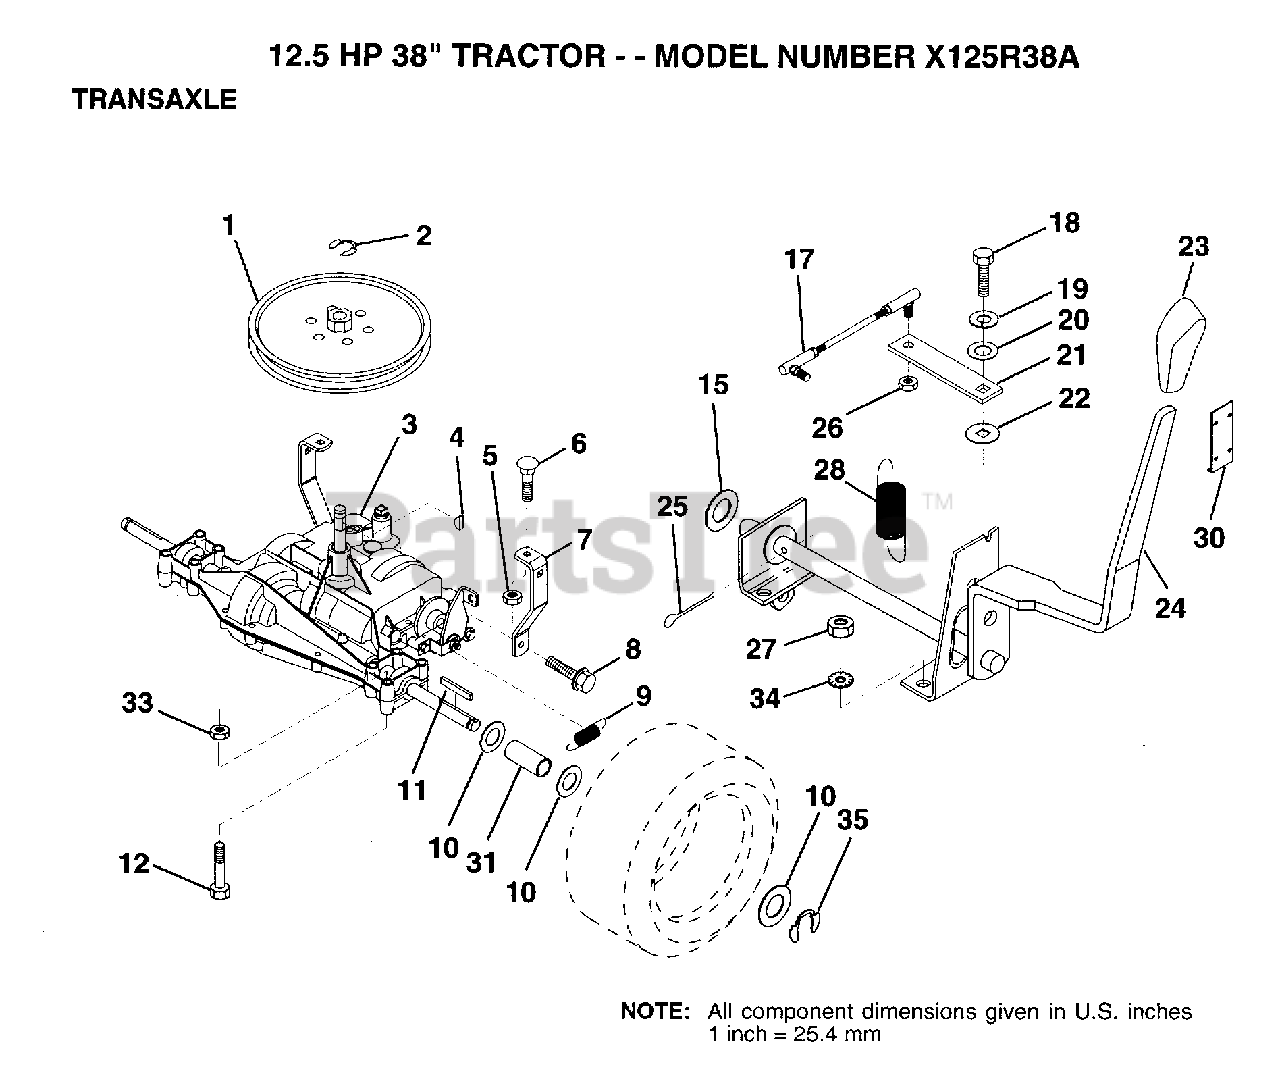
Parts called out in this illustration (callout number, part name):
1	PULLEY
3	TRANSAXLE.6SP.D
6	BOLT
7	"STRAP,TORQUE"
8	SCREW
10	WASHER
11	SQUARE KEY
12	BOLT
17	"LINK,SHIFT"
19	LOCKWASHER
20	WASHER LT
21	"ARM,SHIFT"
22	WASH-SHFT PLT LT
23	"KNOB,SHT CONTROL"
25	PIN COTTER 1/8
26	NUT.LOCK.5/16-24
28	"SPRING,EXT"
30	KNOB RETAINER
31	SPACER
34	LOCKWASHER.5/16.E
35	E-RING LT
